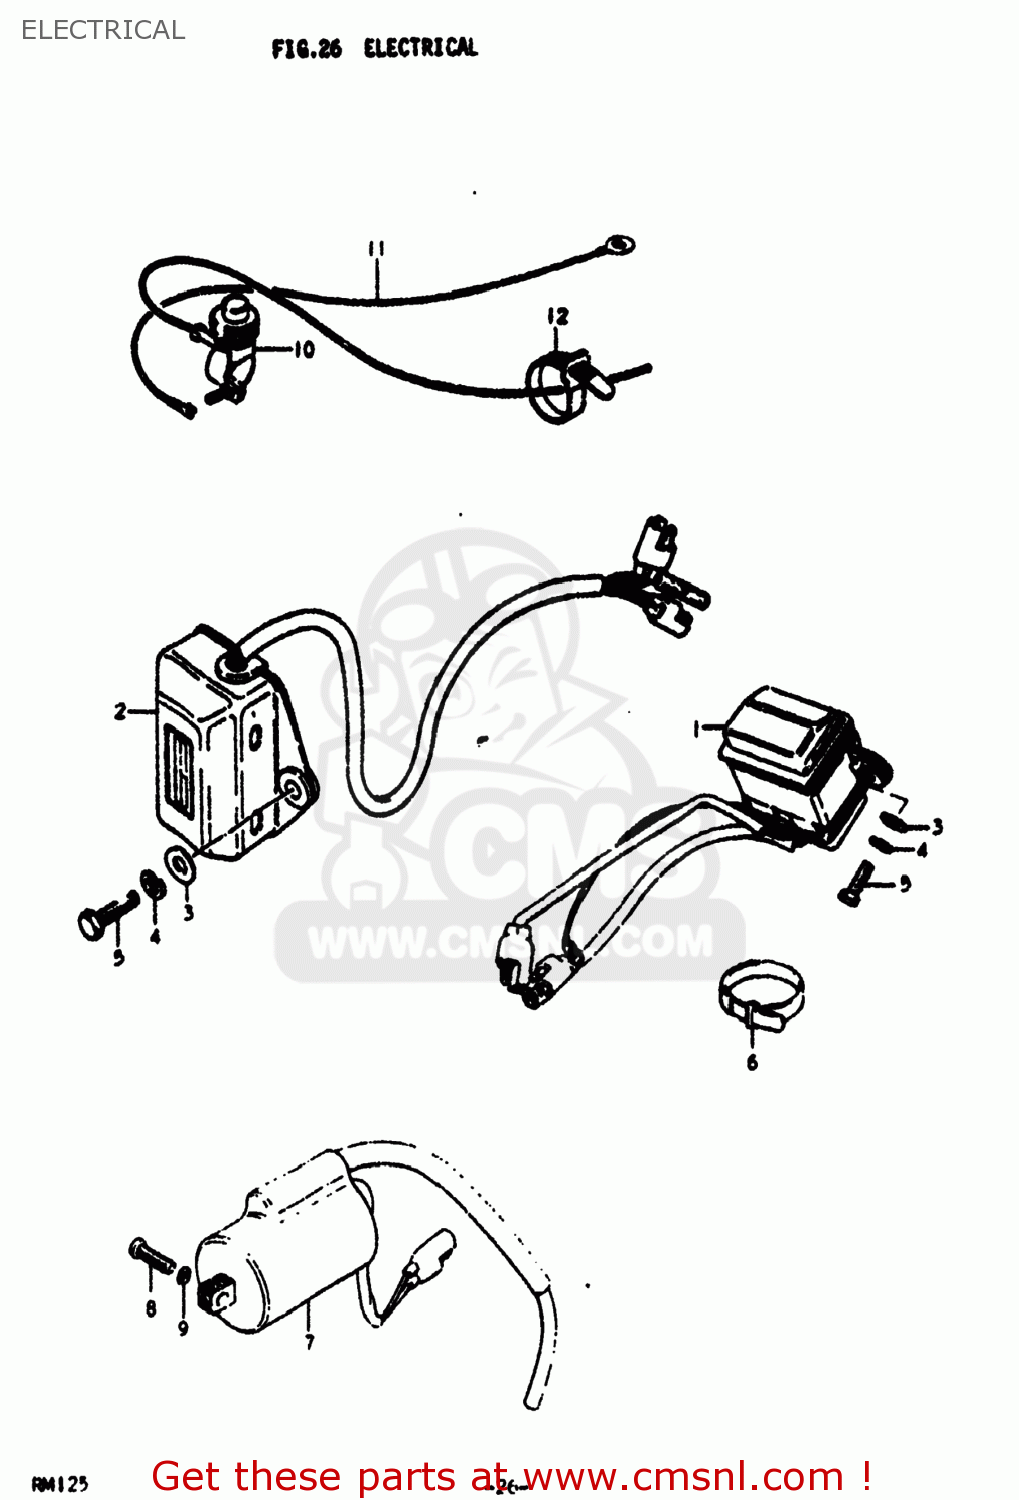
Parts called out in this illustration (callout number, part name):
2	CDI UNIT ASSEMBLY
3	WASHER 6MM
4	LOCK WASHER
5	BOLT
6	CLAMP
7	COIL ASSEMBLY,IGNITION
8	SCREW 5X20
9	LOCK WASHER
10	SWITCH ASSEMBLY
11	WIRE,ENGINE STOP EARTH
12	CLAMP(L:120)
